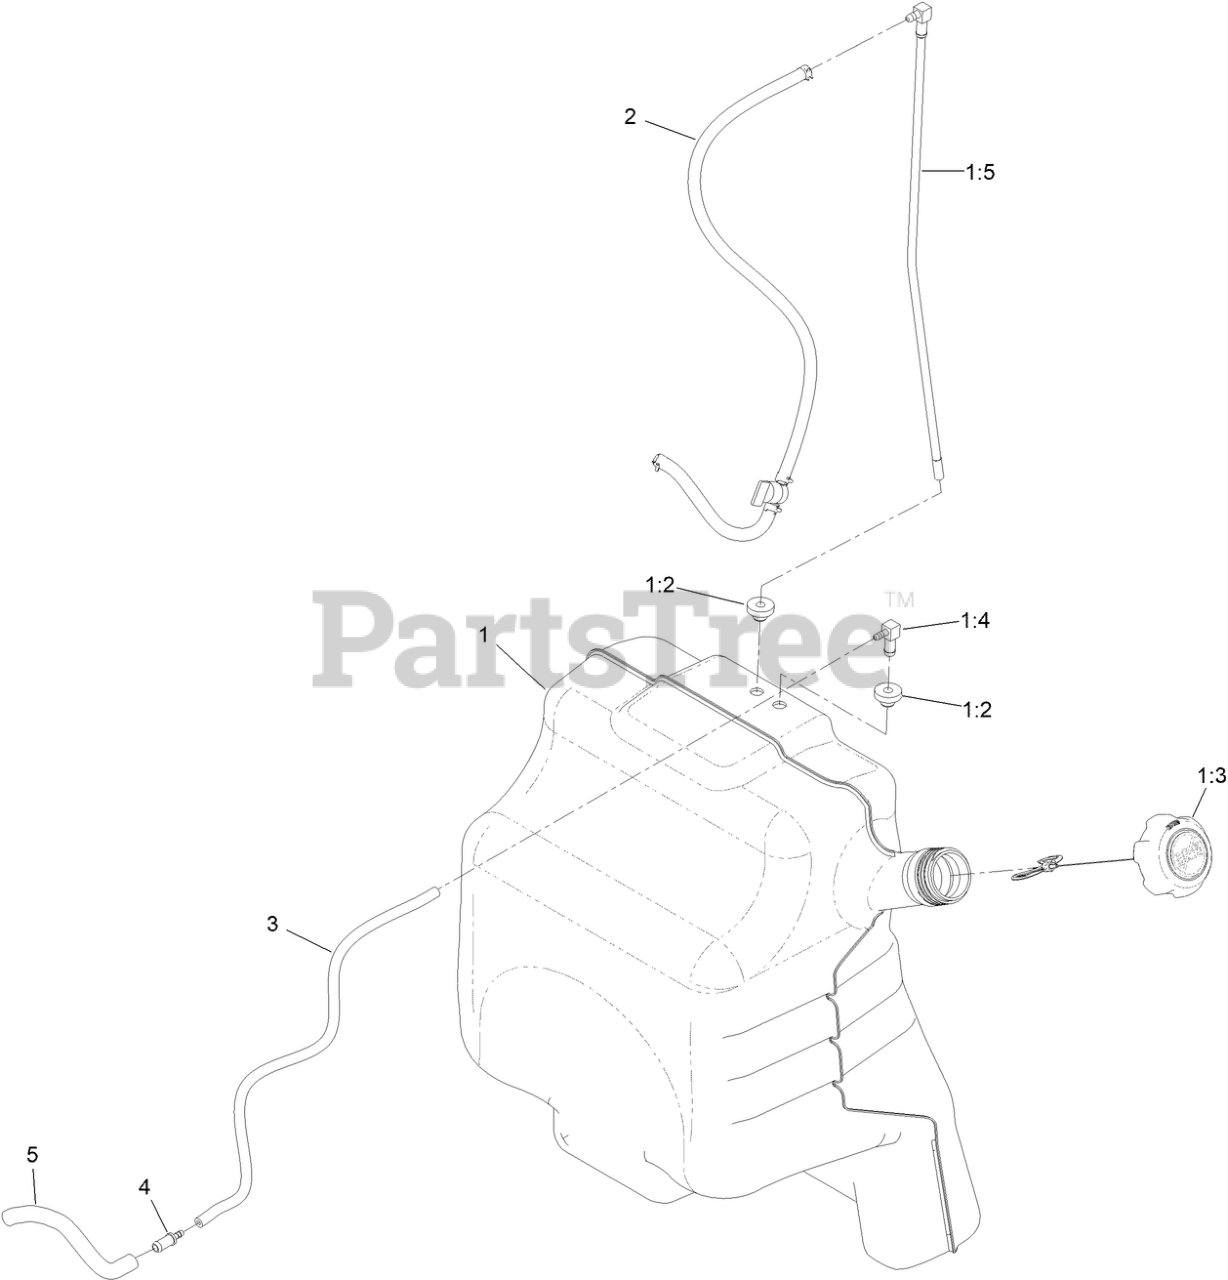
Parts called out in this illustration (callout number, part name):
1	FUEL TANK ASM
1:2	BUSHING
1:3	CAP-FUEL
1:4	FITTING-ELBOW, 90 DEG
1:5	ASM, TUBE-FUEL
2	FUEL LINE ASM
3	HOSE-FUEL
4	FITTING-STRAIGHT
5	HOSE-FUEL
